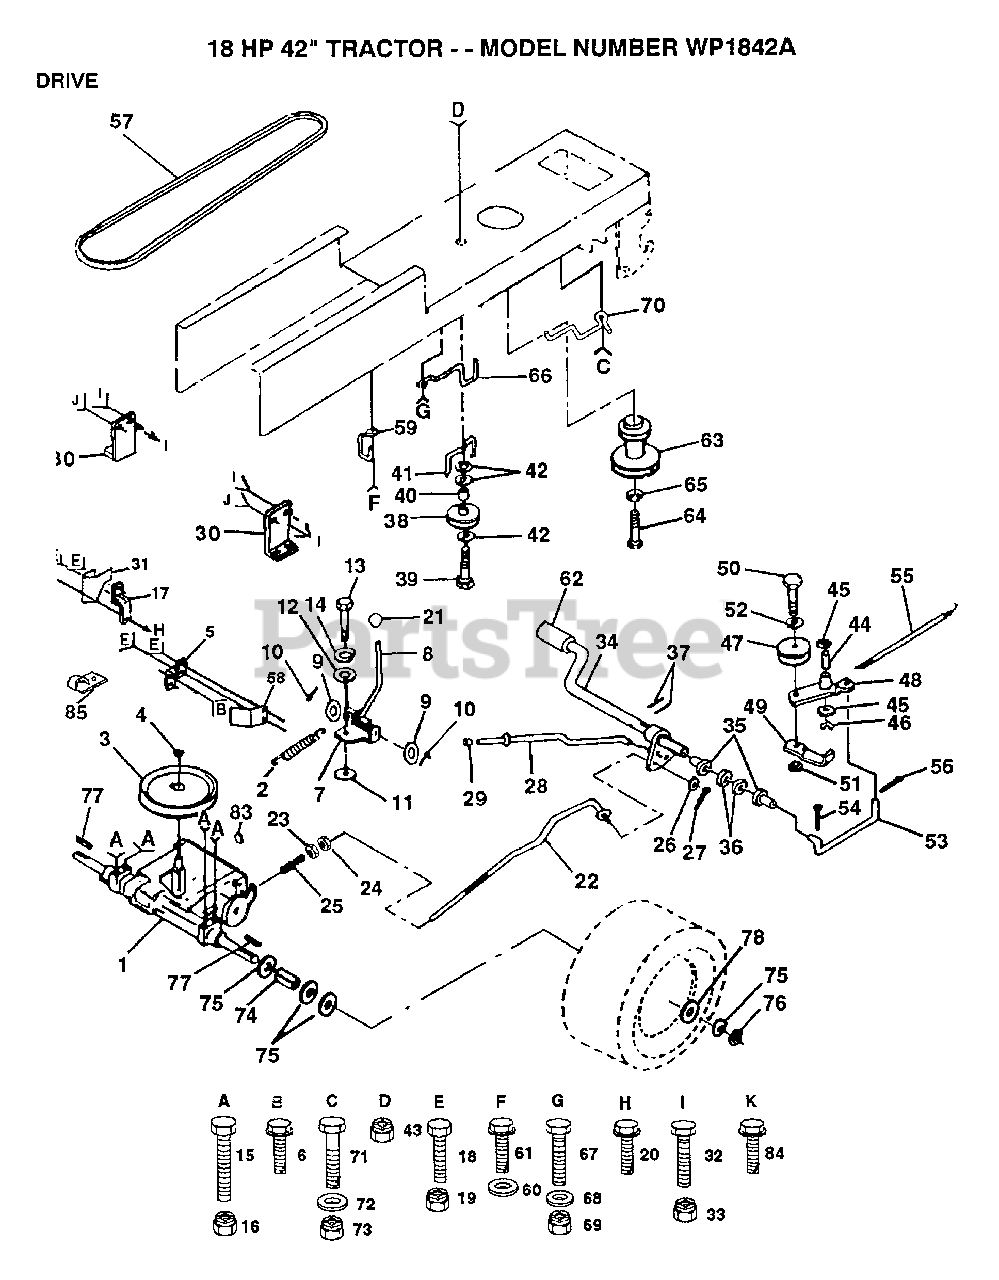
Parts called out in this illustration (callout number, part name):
3	"PULLEY,TRANSAXLE"
5	STRAP TORQUE
6	SCREW
8	SHIFT ROD
9	WASHER
10	PIN COTTER 1/8
11	WASH-SHFT PLT LT
12	WASHER LT
14	LOCKWASHER
15	BOLT
17	STRAP TORQUE
20	SCREW
21	KNOB T (1/2-HOLE)
22	BRAKE ROD
23	NUT
24	NUT
25	SPRING ROD LT
26	WASHER
27	COTTER PIN
28	BRAKE PARK ROD
29	PLUNGER CAP T
30	TRANSAXLE MTG BKT
31	"KEEPER,BELT LH"
32	BOLT
35	NYLON BEARING
36	WASHER LT
38	PULLEY.IDLER.FLAT
39	BOLT
40	SPACER T
41	BELT KEEPER LT
42	WASHER
44	"LY, BEARING"
45	WASHER LT
46	KLIP RING
48	ARM IDLER
49	RETAIN BELT
52	WASHER
53	"LINK, CLUTCH T"
54	COTTER PIN
55	"SPRING, RETURN LT"
56	COTTER PIN
57	BELT-V
58	"KEEPER,BELT RH"
60	WASHER
61	SCREW
62	PEDAL COVER T
64	BOLT
65	LOCKWASHER
66	KEEPER.BELT.ENG.L
67	BOLT
68	WASHER
70	KEEPER BELT ENG
71	BOLT
72	WASHER
74	SPACER LT
75	WASHER
76	E-RING LT
77	SQUARE KEY
78	WASHER
84	SCREW
85	CLIP T
